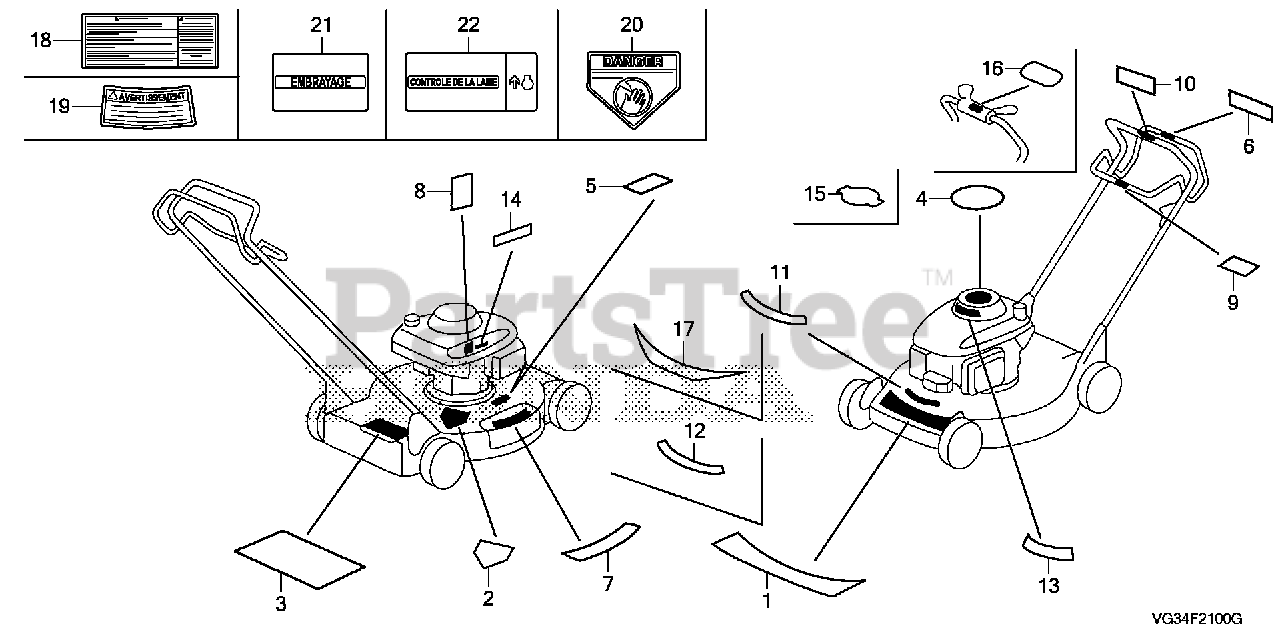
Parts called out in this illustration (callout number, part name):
2	CAUTION C, HOUSING
3	LABEL, WARNING (ENGLISH)
5	LABEL, HEAT WARNING
7	LABEL, DISCHARGE GUARD WARNING (ENGLISH)
9	MARK, BLADE CONTROL (ENGLISH)
11	MARK, MODEL (HRS)
15	MARK, RECOIL COVER
16	MARK, CLUTCH INDICATION (ENGLISH)
17	MARK, HONDA
